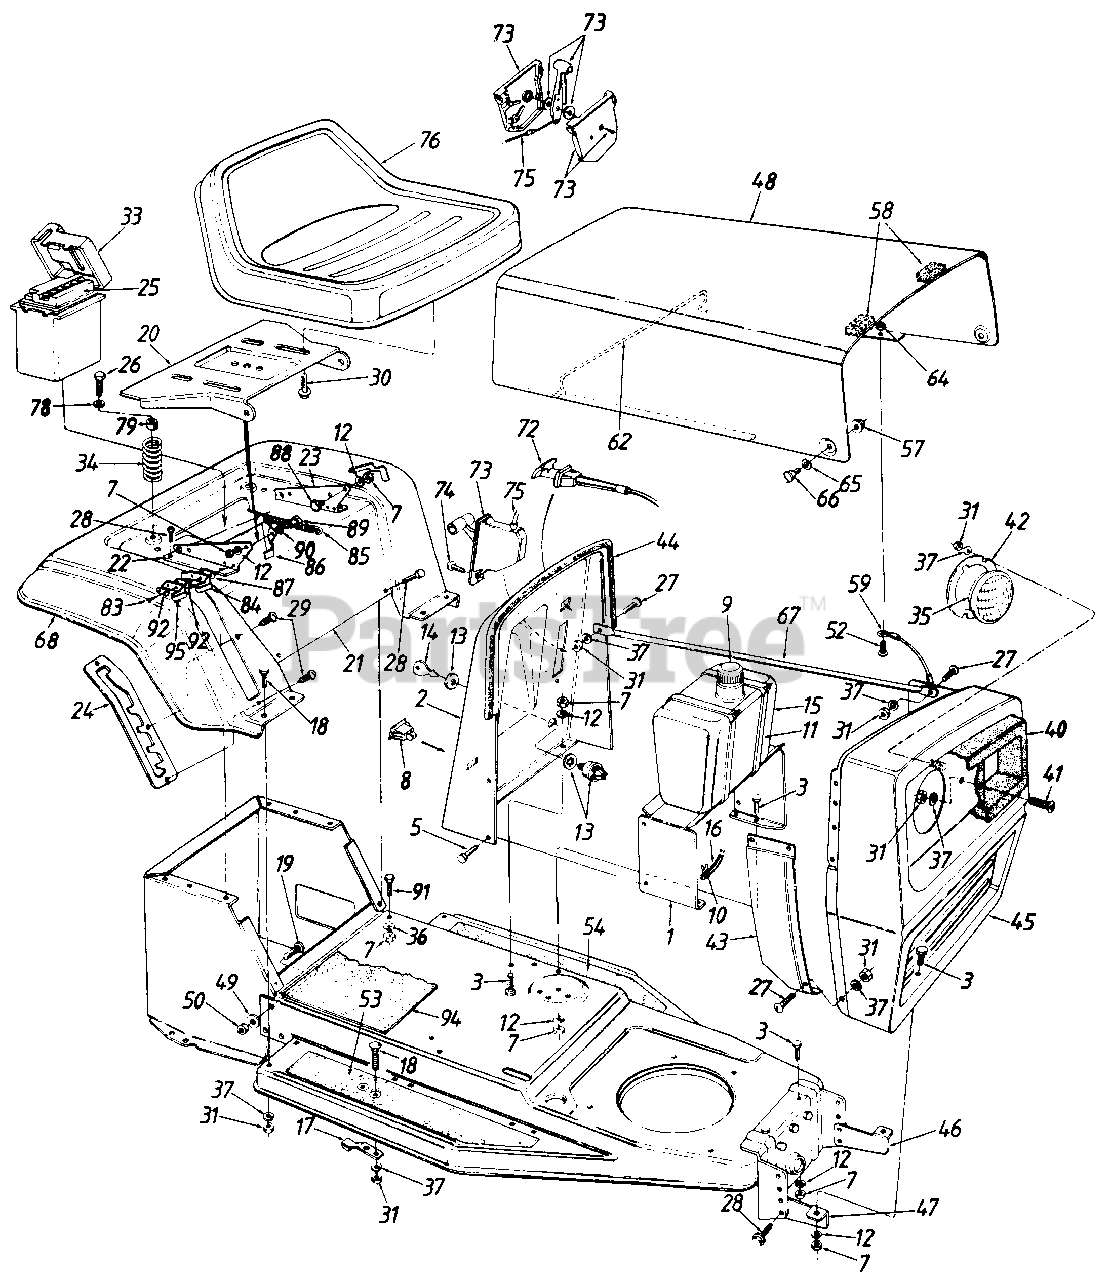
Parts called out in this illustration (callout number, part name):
1	Dash Panel Support Brkt.
5	Hex AB-Tap Scr. 1/4 x .62"
7	Hex Nut 5/16-18 Thd.
8	Light Switch
9	Gas Cap
11	Cable Tie
12	L-Wash. 5/16" I.D.
13	Ignition Switch
14	Ignition Key
15	Fuel Tank
16	Gas Line-15" Lg.
17	Blade Brake Ass'y.
18	Carriage Bolt 1/4-20 x .62"
19	Ribbed Neck Bolt 3/8-24 x .8"
20	Seat Pivot Brkt.
25	Battery
26	Hex Self-Tap Screw 5/6-18 x 1.25" Lg.
27	Truss Mach. Scr. 1/4-20 x .75" Lg.
28	Hex AB-Tap Scr. 5/16 x 75" Lg.
29	Torx Mach. AB-Tap Scr. 1/4 x .62" Lg.
30	Hex Self-Tap Scr. 3/8-16 x .75" Lg.
31	Hex Nut 1/4-20 Thd.
33	Battery 8Ox w/Cover
34	Compression Spring
35	Headlight
36	Bell-Wash. 5/16" I.D.
37	L-Wash. 1/4" I.D.
41	C-Sunk Mach. Scr. 1/4-20 x 1.5n
42	Headlight Retainer
43	Side Panel-R.H.
44	Trim Strip 31" Lg.
47	Grille Mtg. Brkt.-R.H.
50	Hex L-Nut 3/8-24 Thd.
52	Truss Mach. Scr. #10-24 x .5" Lg.
53	Foot Pad-R.H.
54	Foot Pad-L.H.
57	Lock Nut 1/4-28 Thd.
64	Hex Sems Nut #10-24 Thd.
65	Spr. Wash. .39" l.D. x .62" O.D.
66	Shld. Bolt
67	Grille Support
68	Trim Strip 81" Lg.
72	Choke Control
73	Throttle Control Box
74	Truss AB-Tap Scr. #10 x .5"
75	Throttle Wire
76	Seat Assembly
78	Flat Wash. .344" l.D. x .8811 O.D.
83	Hex Tap Scr. #8 x .51' Lg.
84	Safety Switch
85	Ext. Spring 5.31" Lg.
86	Seat Lift Brkt.
87	Insulator Boss Plate
88	Shld. Bolt .437" Dia. x .162" Lg.
89	Shld. Bolt .437" Dia. x .268" Lg.
90	Spr. Wash. .445" l.D. x .75" O.D.
91	Hex Wash. Hd. Scr. 5/16-18 x .62" Lg.
92	Insulator Plate
94	Foot Pad-Center
95	Safety Switch
